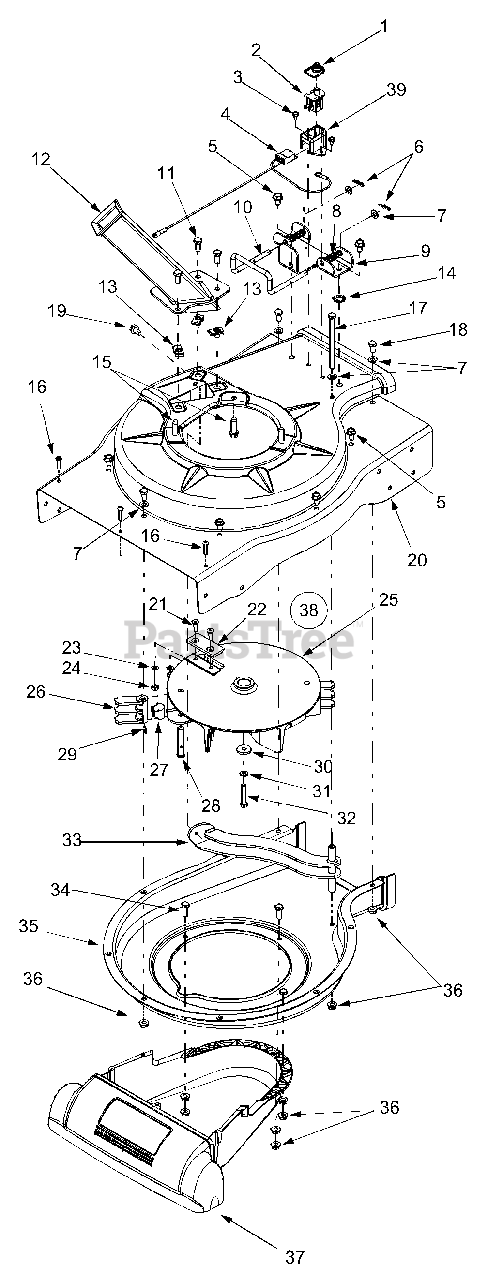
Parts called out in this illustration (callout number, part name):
1	Switch Cover
2	Safety Switch
3	Hex Washer Screw #10-16 x.50
4	Wire Harness
5	Hex Washer Screw 5/16-18 x.625
6	Cotter Pin
7	Flat Washer.330 ID x.630 OD
8	Compression Spring
10	Lock Rod
11	Hex Cap Screw 5/16-18 x.75
13	U-Clip Lock Nut 5/16-18
14	External Lock Washer 5/16
15	Hex Washer Screw 3/8-16 x 1.25
16	Screw #12-16 x 1.0
17	Hex Cap Screw 5/16-18 x 4.5
18	Hex Cap Screw 5/16-18 x.625
19	Hex Washer Screw 5/16-18 x.625
22	Chipper Blade
23	Lock Washer 5/16
24	Hex Lock Nut 5/16-24
25	Impeller Weldment
26	Flail
27	Pin Clip
28	Clevis Pin
29	Spiral Pin
30	Flat Washer.375 ID x 1.25 OD
31	Lock Washer 3/8
32	Hex Cap Screw 3/8-24 x 2.0
34	Hex Cap Screw 5/16-18 x.875
36	Lock Nut 5/16-18
37	Nozzle Cover
38	Impeller Assembly
39	Safety Switch Cover
